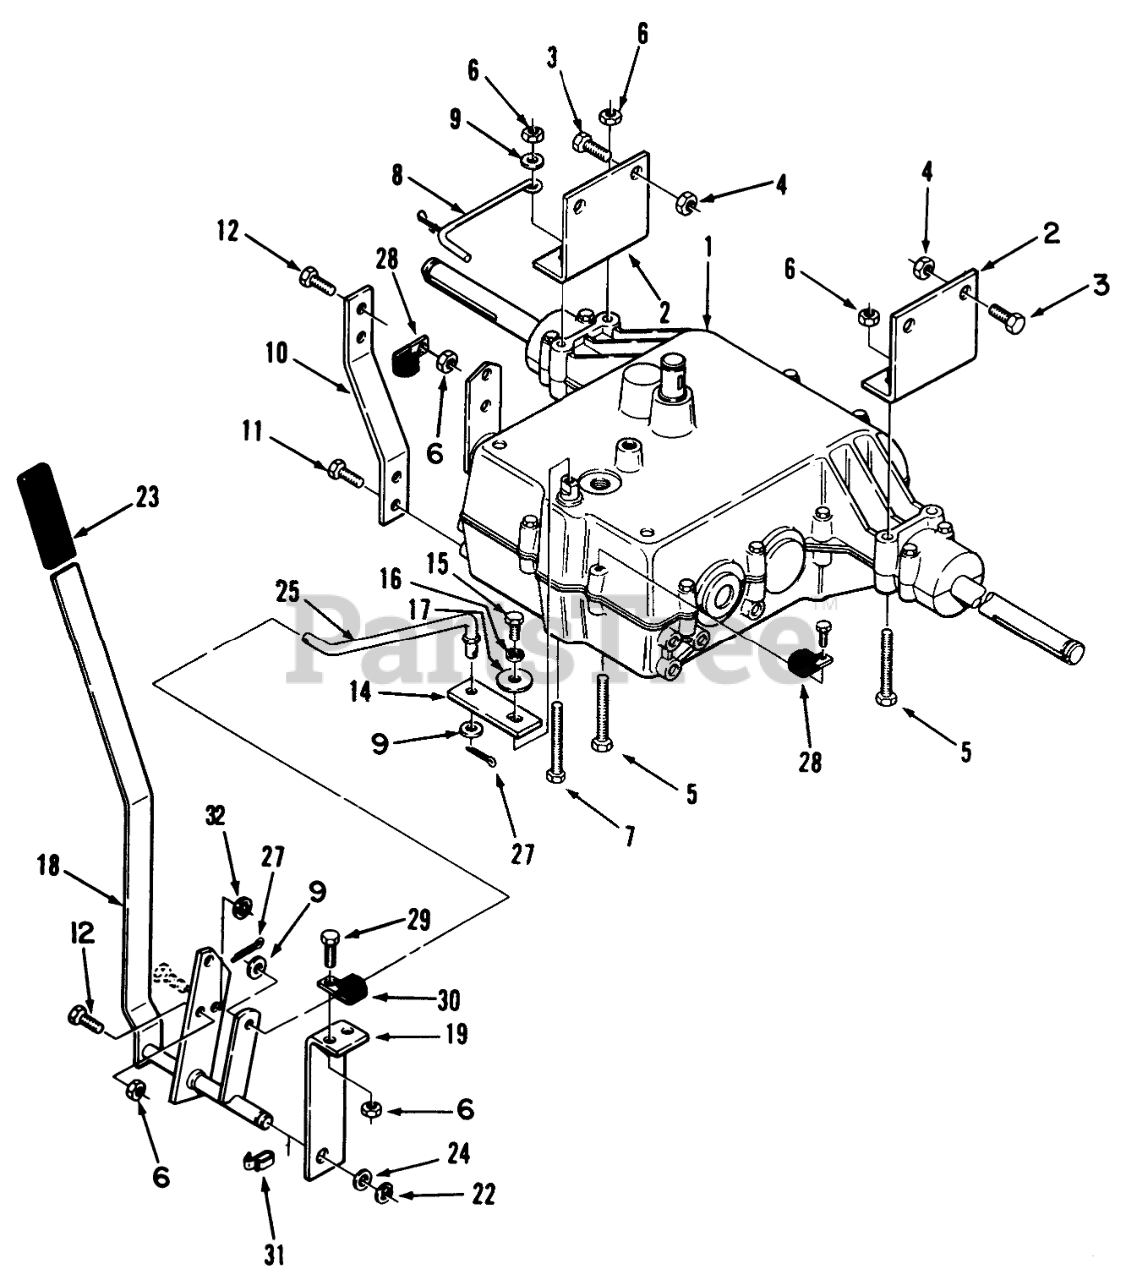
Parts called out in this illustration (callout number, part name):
1	TRANSAXLE-4SPD 930
2	Bracket-Rear Axle
3	BOLR HWH 3/8-16X7/8
4	NUT-LOCK, NI
5	SCREW-HH
6	NUT-LOCK, NI
7	SCREW-HH
8	STOP BRAKE
9	WASHER-PLAIN
10	STRAP TORQUE
11	HEX WASH HD SCREW
12	SCREW-HH
14	LEVER LOWER SHIFT
15	SCREW-HH
16	WASHER-LOCK
17	WASHER
18	ASSY LEVER SHIFT R
19	SUPPORT SHIFT
22	RING-RETAINING, EXTERNAL
24	Washer
25	ROD SHIFT LOWER
27	PIN-COTTER
28	J-CLIP
29	BOLT 5/16-18 X 3/4
30	J-CLIP
31	CLIP-CABLE
32	Lockwasher
